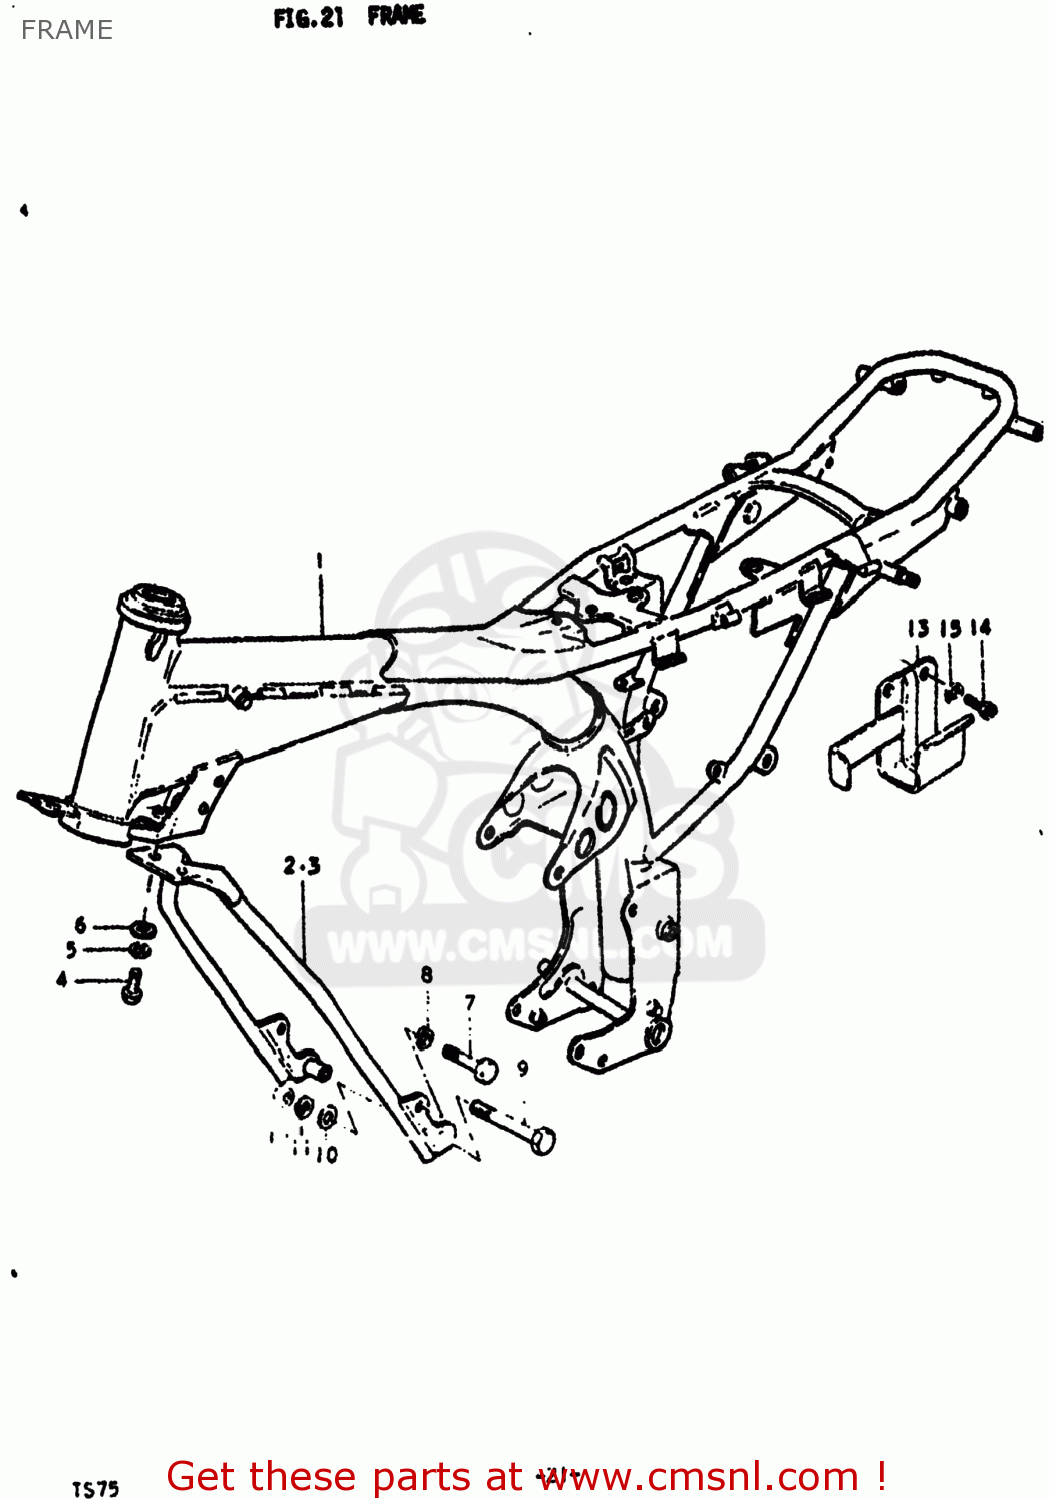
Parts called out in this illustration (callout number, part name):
1	FRAME
4	BOLT
5	LOCK WASHER
6	WASHER 6MM
7	BOLT
8	LOCK WASHER
9	Bolt 8X50
10	WASHER
11	LOCK WASHER
12	NUT
13	HOLDER,TOOL
14	BOLT
15	LOCK WASHER
